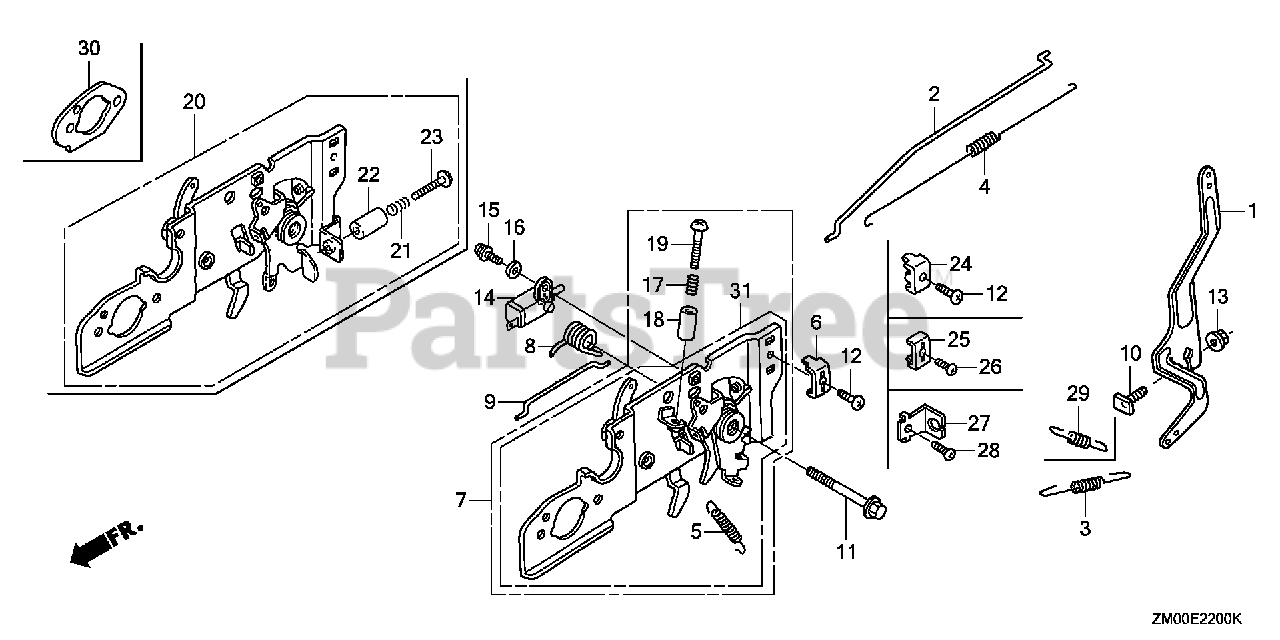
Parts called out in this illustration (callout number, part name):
1	ARM, GOVERNOR
2	ROD, GOVERNOR
3	SPRING, GOVERNOR
4	SPRING, THROTTLE RETURN
5	SPRING, LEVER
9	ROD, CHOKE
10	BOLT, GOVERNOR ARM
11	BOLT, FLANGE (6X50)
12	SCREW, PAN (5X16)
13	NUT, FLANGE (6MM)
24	HOLDER, CABLE
31	BASE, CONTROL
